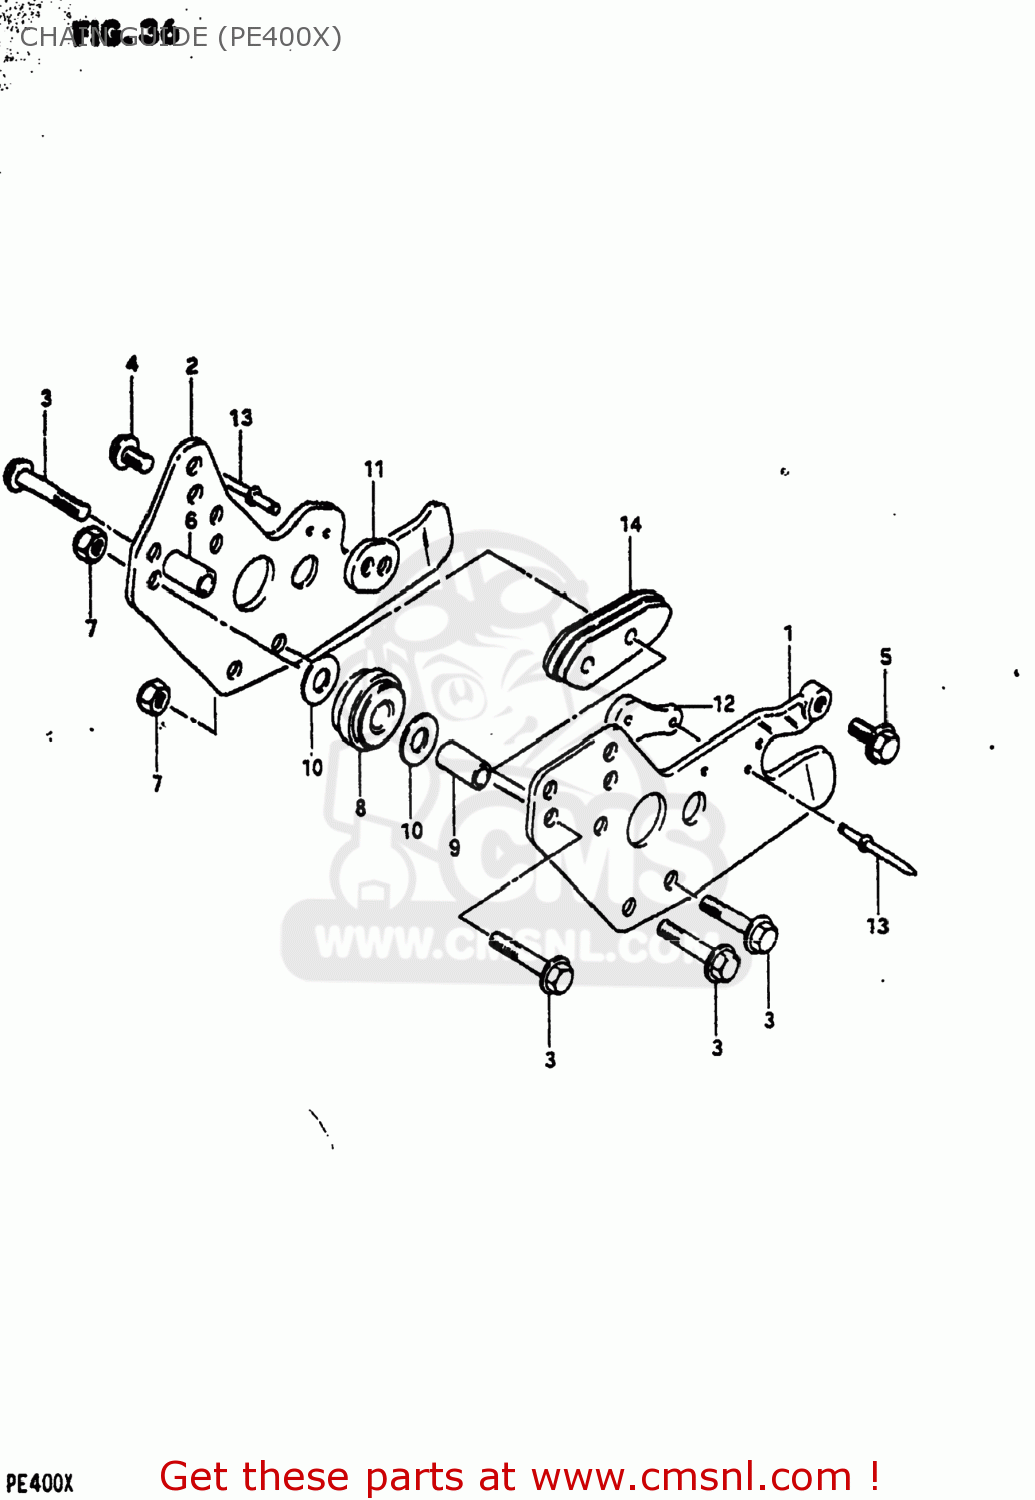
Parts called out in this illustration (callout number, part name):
1	PLATE,CHAIN GUIDE,OUTER
2	PLATE,GUIDE CHAIN
3	BOLT
4	BOLT
5	BOLT
6	SPACER(6.8X10X24.2)
7	NUT
8	ROLLER,CHAIN GUIDE
9	SPACER,CHAIN GUIDE ROLLER
10	WASHER
11	PAD,DRIVE CHAIN GUIDE
12	PAD,DRIVE CHAIN GUIDE
13	RIVET
14	DEFENSE,CHAIN GUIDE
